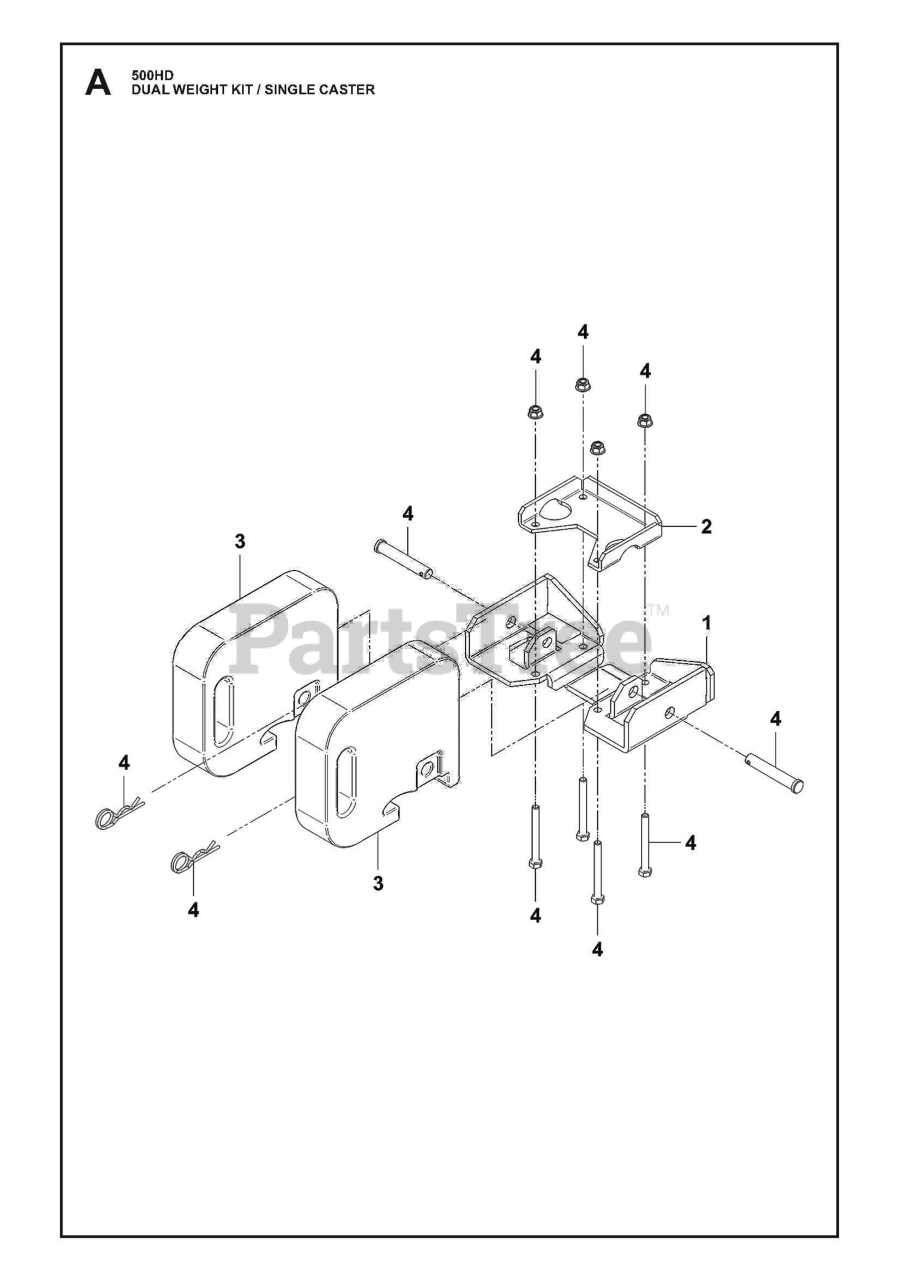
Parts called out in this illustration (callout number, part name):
1	BRACKETS
2	CLAMPS
3	WEIGHTS
4	WEIGHTS
